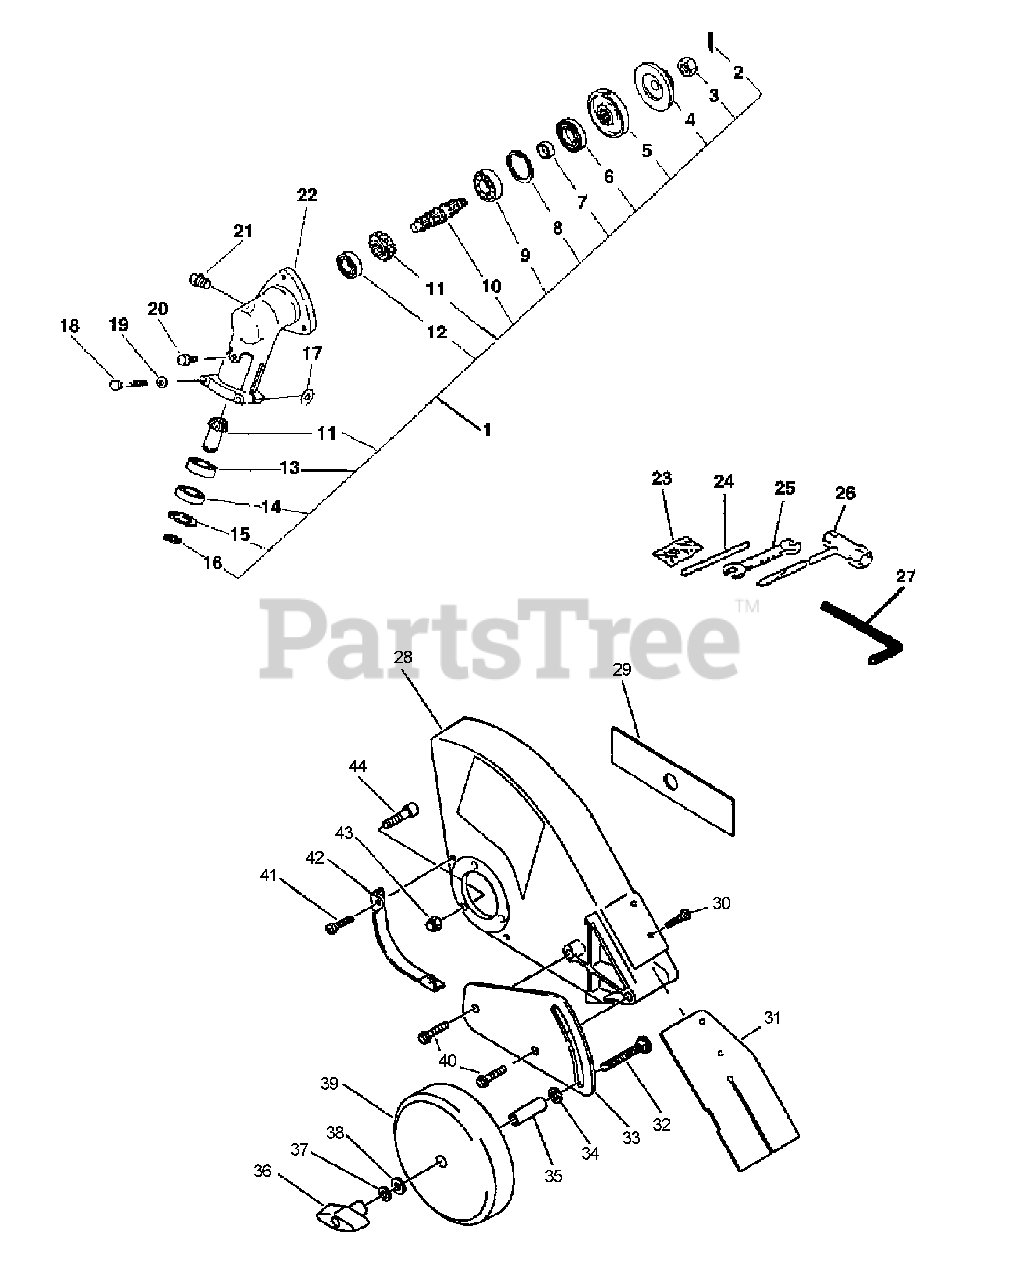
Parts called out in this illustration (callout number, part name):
1	GEAR CASE ASSY
2	PIN, COTTER 2×22
4	PLATE, ADAPTOR - LOWER
5	PLATE, ADAPTER - UPPER
6	SEAL, OIL 22
7	SPACER 11.8×15×9
8	RING, RETAINING - 32
9	BEARING, BALL - 6201 C3
10	SHAFT, GEAR
11	GEAR SET
12	BEARING, BALL 609
13	BEARING, BALL 6900
14	BEARING, BALL 6900Z
15	RING, SNAP Ø22
16	RING, SNAP Ø12
18	WASHER, FLAT 5.5×10×0.8
19	BOLT 5×35 SP
20	BOLT - 5×8
21	SCREW 5×10
22	HOUSING, GEAR CASE
23	PIN, COTTER 2×22 (PKG. OF 10)
24	TOOL, LOCKING 5×120 MM
25	SPANNER 8×10
26	T-WRENCH 17x-19 L200
27	WRENCH, ALLEN 3 MM
28	SHIELD, DEBRIS
29	BLADE - 2 PK
31	FLAP, DEBRIS
32	BOLT 5/16"-18×2-1/2"
33	BRACKET, WHEEL
34	WASHER, SPRING 10
35	COLLAR 12
36	KNOB, FASTENER
37	WASHER, SPRING 8
39	WHEEL
42	GUARD, SHIELD
43	NUT, LOCK M5
44	BOLT 5×22
